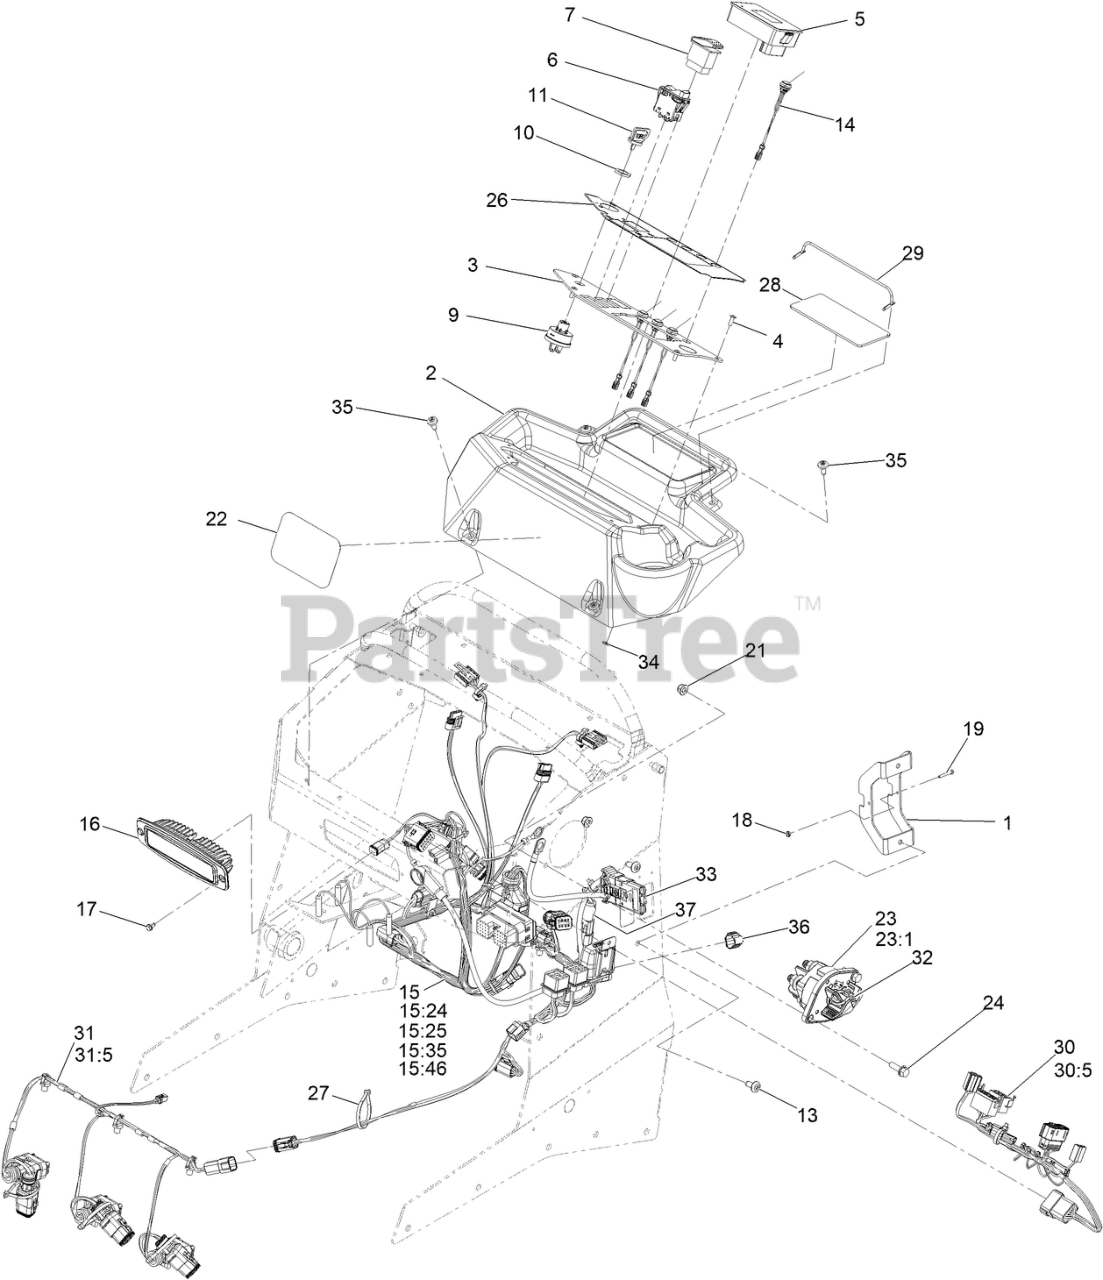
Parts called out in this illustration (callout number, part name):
1	BRACKET-CHARGER, DUAL
2	DASH-CONTROL PANEL
3	PLATE-CONTROL PANEL
4	RIVET-POP
5	MODULE-DISPLAY
6	SWITCH-ROCKER, (ON)-ON-OFF
9	SWITCH-KEY, SPST
11	KEYS-IGNITION (SPARE PAIR
11	KEY-IGNITION
14	SWITCH-PUSHBUTTON
15	HARNESS-WIRE, MAIN
15:24	FUSE-MINI BLADE, 2 AMP
15:35	Fuse-Blade, 10A
15:46	Fuse-Mini Blade, 7.5 Amp
16	MOUNT-FLUSH, LIGHT
17	SCREW-HWH
18	NUT-HEX
19	SCREW-HH
21	NUT-HF, NI
22	DECAL-X-LOGO
23	SWITCH-DISCONNECT
24	SCREW-HHF
26	Decal-Panel, Control
27	TIE-CABLE
28	PAD-RUBBER, W/ADHESIVE
29	STRAP-ELASTIC
30	HARNESS-WIRE, CONTROL PANEL
30:5	RESISTOR-120 OHM
31	HARNESS-WIRE, DECK
31:5	RESISTOR-120 OHM
32	TIE-CABLE
33	HARNESS-WIRE, CHARGER PORT
34	WASHER-PLAIN
35	SCREW-SHOULDER
36	CAP-PLUG, 3 WAY
37	FERRITE-SNAP ON
